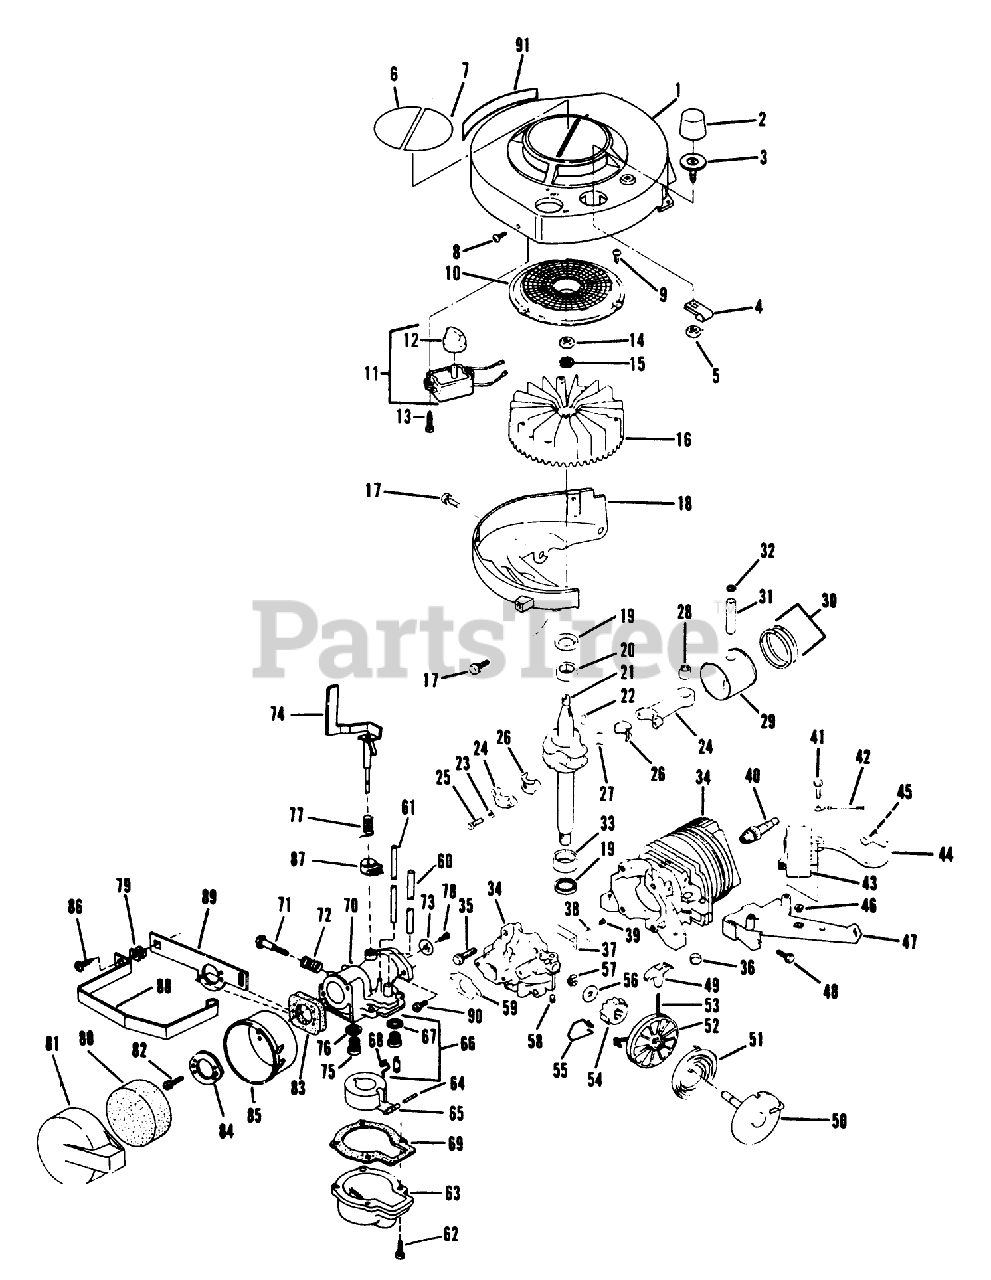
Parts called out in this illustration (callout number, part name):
5	LOCKNUT S
8	SCREW F
9	SCREW F
12	SWITCH KNOB
14	NUT
17	SCREW-SEMS
20	BEARING V
22	KEY
25	SCREW
26	LINER ASM
28	BEARING AY F
32	RING-RETAINING
33	BEARING V
35	SCREW S
36	PLUG-CORE VF
38	PLATE-BACKUP, REED
44	HT LEAD&COVER XEV
46	NUT-CLIP
49	HANDLE STARTER S
51	SPRING S
55	SPRING F
56	WASHER S
58	SET SCREW
59	GASKET CARB S
61	TUBING PRIMER S
67	WASHER
71	SCREW S
72	SPRING S
75	PLUG S
76	WASHER
78	SCREW F
79	NUT-CLIP
80	AIR FIL.ELEM S
82	SCREW S
83	GASKET S
84	WASHER S
86	SCREW S
87	CLAMP-SPR ADJ S
88	STRAP S
90	SCREW S
